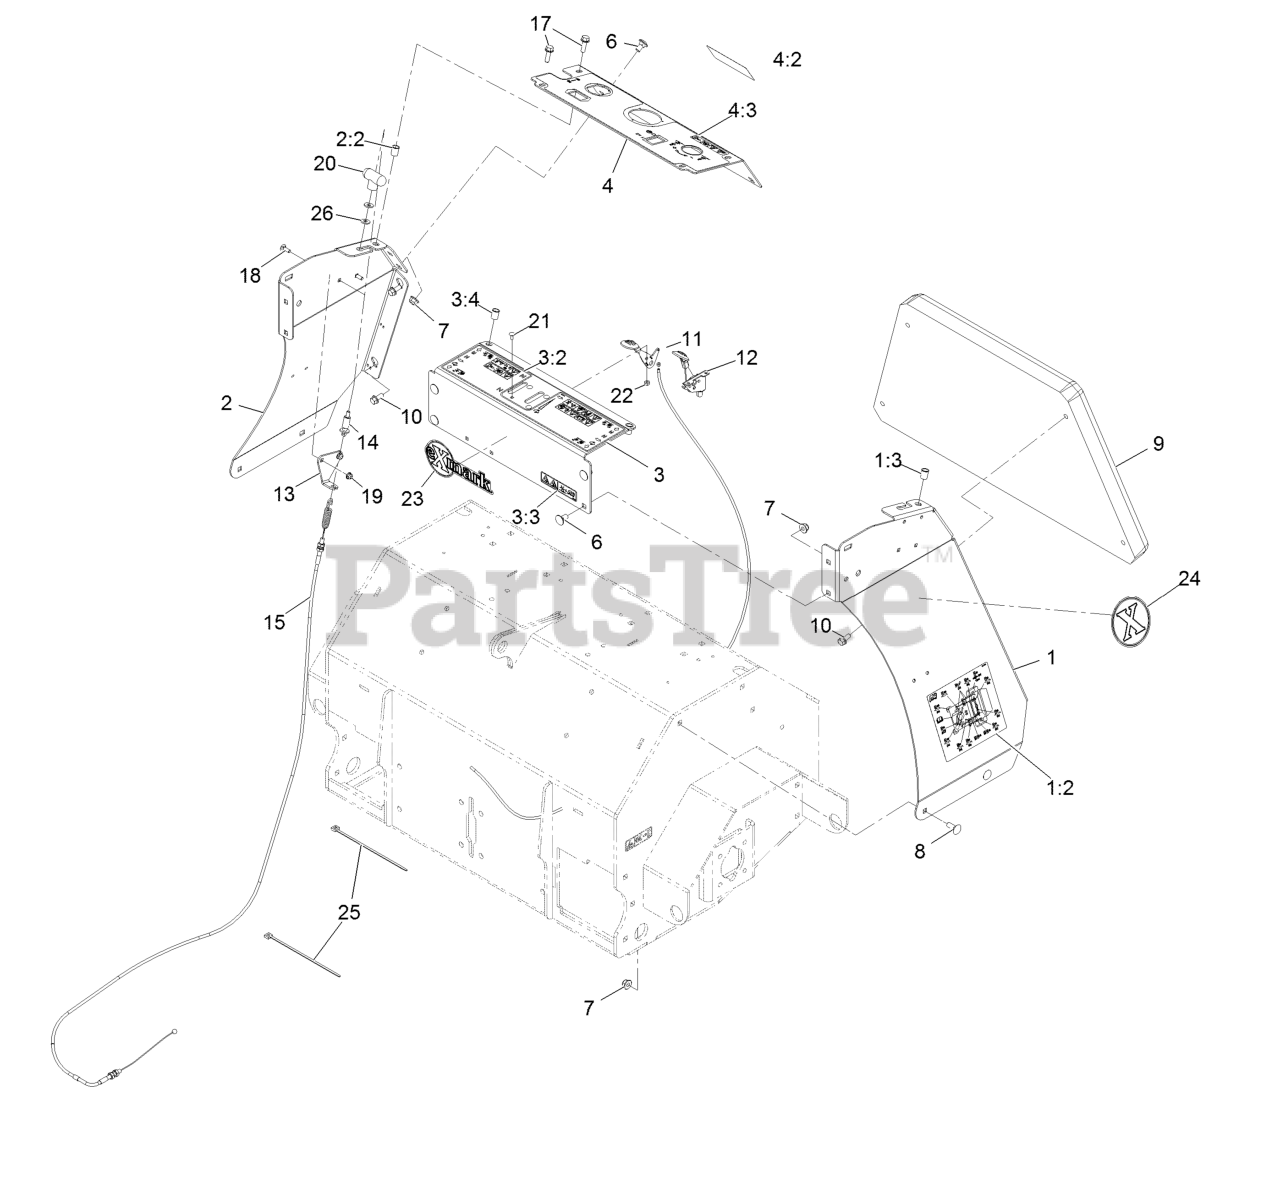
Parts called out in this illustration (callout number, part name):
1	Panel-Side,LH W/Decals-Black
1:2	Decal-Service Aid CE
1:3	Nut-Insert
2	ASM-Panel,Side RH (Black)
2:2	Nut-Insert
3	ASM-Plate W/Decal
3:2	Decal-Warning, Control Panel
3:3	Decal-Warning, Tines
3:4	Nut-Insert
4	ASM-Panel W/Decals
4:2	Decal-Warning
4:3	Decal-Danger, Control Panel
6	Bolt-Carriage 3/8-16 X 3/4
7	Nut-Nyloc 3/8-16 Flg
8	Bolt-Carriage 3/8-16 X 1
9	Cushion, Grey
10	Screw-HH Flg 5/16-18 X 3/4
11	Control-Choke
12	Control-Throttle
13	Bracket-Cable, Brake
14	Link-Cable, Brake
15	Cable-Brake
17	Screw-HH Flg 5/16-18 X 1
18	Bolt-Carriage 1/4-20 X 3/4
19	Nut-Nyloc 1/4-20 Flg
20	Knob-Tee
21	Bolt-Carriage #10-24 X 1/2
22	Nut-Nyloc #10-24
23	Decal, Exmark Logo
24	Decal-X-Logo
25	Tie-Cable 7 15/16 (Large)
26	Washer-1/4 Std
